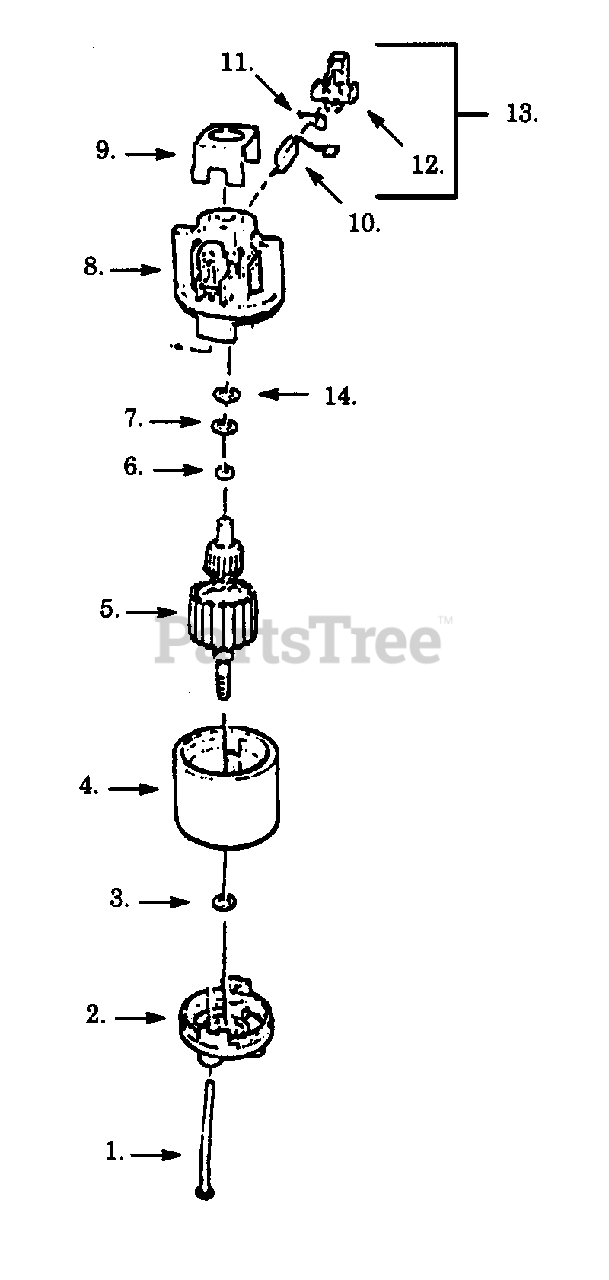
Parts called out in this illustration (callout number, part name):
2	Endbell Ass'y. (Drive)
4	Field Ass'y.
5	Armature Ass'y.
8	Endbell Ass'y. (Brush)
9	Insulator
10	Carbon Brush
11	Brush Spring
12	Brush Holder
13	Brush Kit
14	Retaining Ring
